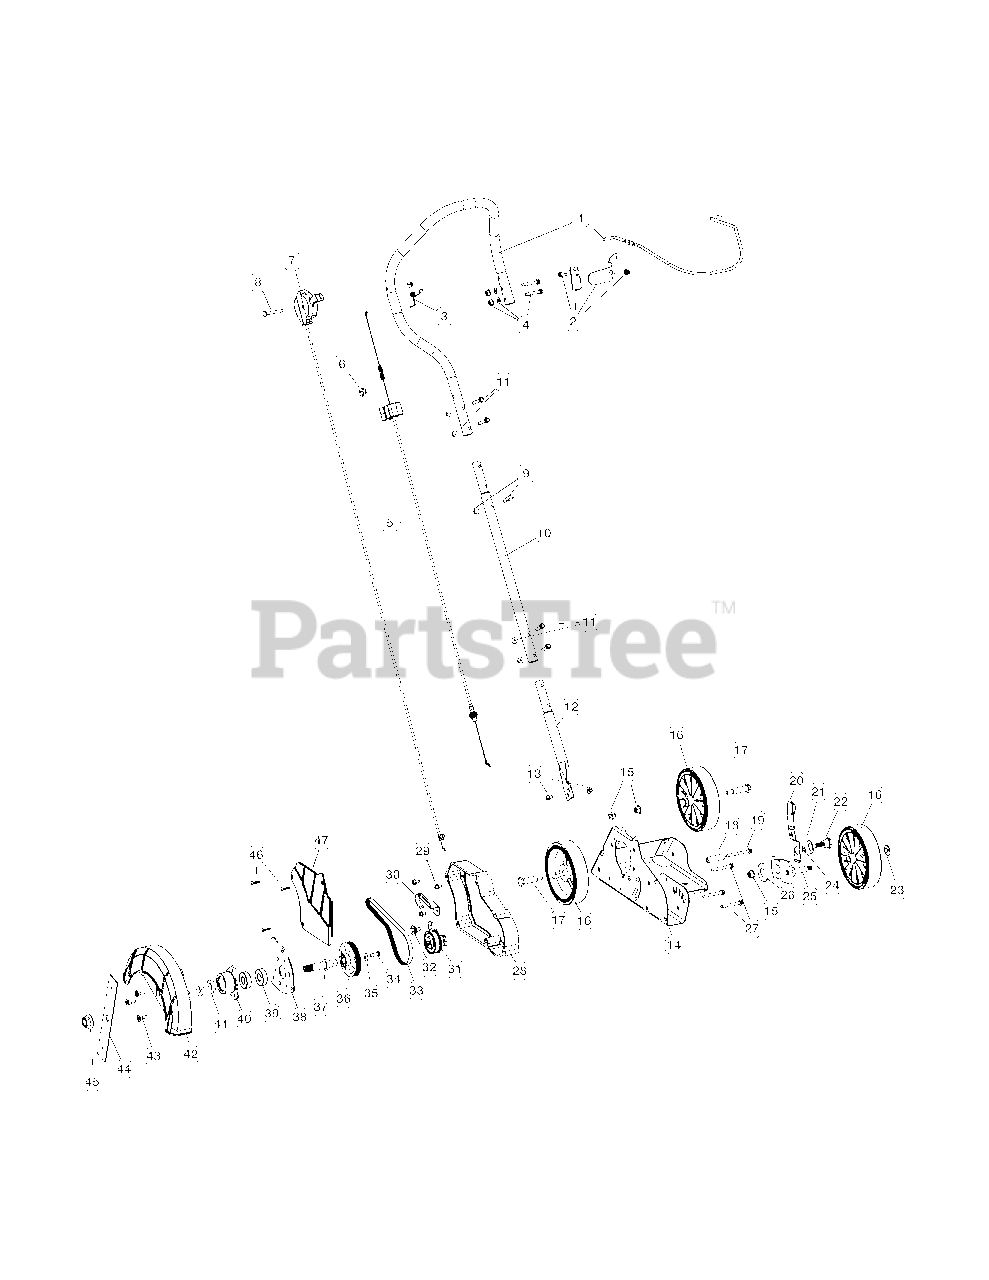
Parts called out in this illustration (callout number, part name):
1	Handle Assembly
2	Lockout Lever Assembly
3	Bale Spring
4	Lockout Hardware Assembly
5	Tensioner Cable Assembly
7	Throttle Assembly
8	Throttle Hardware Assembly
9	Starter Rope Guide Assembly
10	Middle Handle Assembly
11	Handle Hardware Assembly
12	Lower Handle
13	Lower Handle Screw & Nut Assembly
14	Edger Frame
15	Lock Nut
16	Wheel
17	Wheel Bolt
18	Spacer
19	Spacer Screw
20	Height Adjustment Lever Assembly
21	Washer
22	Shoulder Screw
23	Nut
24	Washer
25	Pivot Arm
26	Height Adjustment Spacer
27	Spindle Plate Screw
28	Spindle Spacer
29	Screw
30	Belt Retainer
31	Idler Pulley Assembly
32	Shoulder Screw
33	Belt
34	Screw
35	Washer
36	Pulley
37	Blade Spindle
38	Spindle Plate
39	Bearing
40	Bearing Cup
41	Washer
42	Blade Guard
43	Screw
44	Edger Blade
45	Nut
46	Screw
47	Belt Cover
